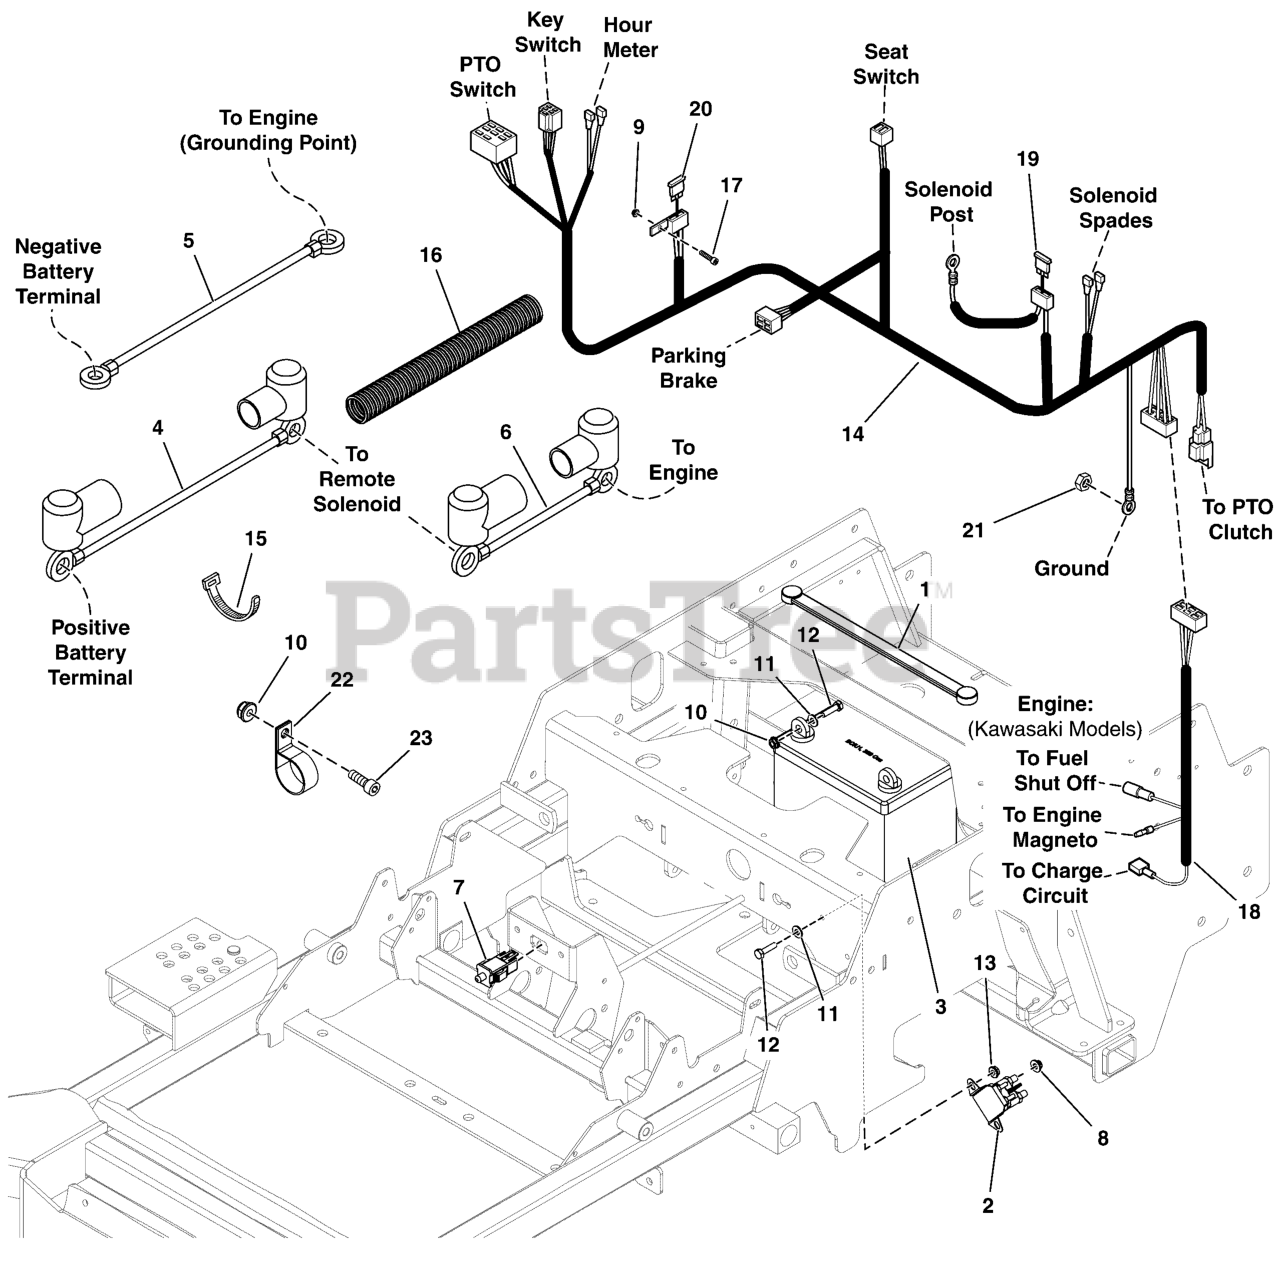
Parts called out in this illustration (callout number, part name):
1	STRAP, BATTERY, 14 LONG, Rubber
2	SOLENOID, STD-BRACKET, 2-SPADE
3	BATTERY, 11U1L, 350 CCA
4	BATTERY CABLE, POS, 22, 1/4-5/16
5	BATTERY CABLE, NEG, 14, 5/16-13/32
6	BATTERY CABLE, POS, 22, 1/4-5/16
7	SWITCH, DP NO/NC SNAP-IN
8	NUT,1/4-20,KEPS,CONICAL WSHR,ZC/CL
9	NUT, Hex, Nylon Lock, #10-24
10	NUT, 1/4-20 HEX SERR. FLANGE
11	WASHER, 1/4 SAE
12	BOLT, 1/4"-20 X 3/4" GD5 YZ
13	NUT, 1/4-20 Hex Nylock Flange
14	HARNESS, Wiring, Small ZTR
15	TIE, SELF-LOCKING, 12"
16	WIRE LOOM, 3/8 ID X 18 IN
17	SCREW, #10-24 X 3/4" ROUND PHILLIPS
18	WIRE HARNESS, JUMPER, KAWI
19	FUSE, ATO-20 (20 AMP)(SV)
20	FUSE, ATO-15 (15 AMP)(SV)
21	NUT, M8-1.25 Hex Serrated Flange
22	CLAMP, VINYL INSULATED, 1.00
